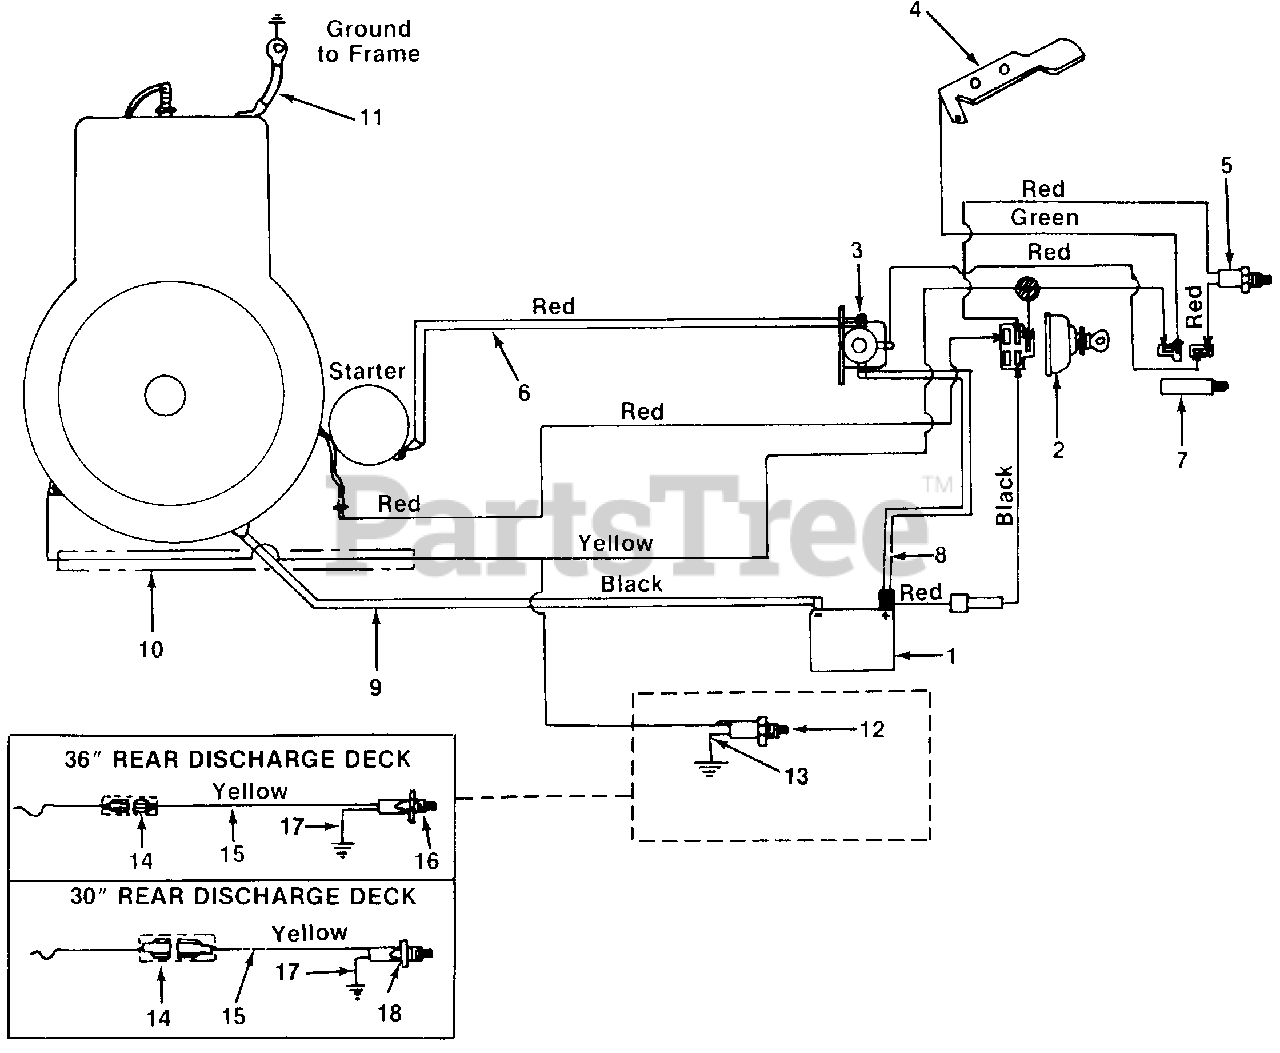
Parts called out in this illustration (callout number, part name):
1	Battery
2	Key Switch
3	Solenoid
4	Spring Switch
5	Safety Switch
6	Electric Wire
7	Safety Switch
8	Electric Wire-13.5" Lg.
9	Ground Wire
10	Convoluted Conduit-24" Lg.
11	Ground Wire
12	Safety Switch
13	Ground Wire
14	Tab Receptacle
15	Wire Lead-12" Lg.
16	Safety Switch
17	Ground Wire
18	Safety Switch
